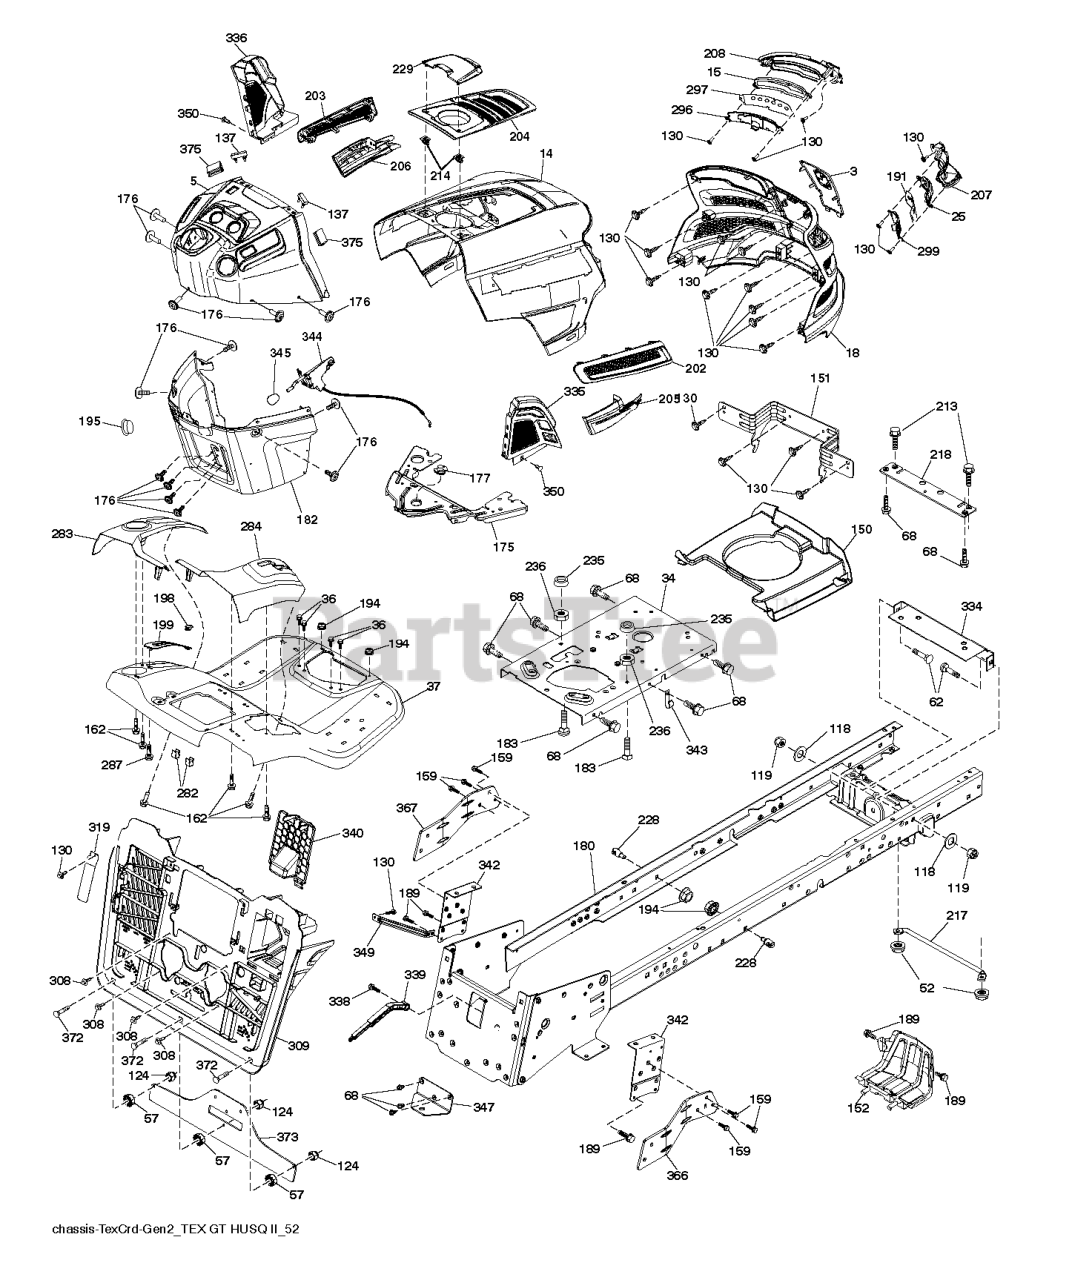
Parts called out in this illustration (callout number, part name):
3	APPLIQUE.SUBASM.GT.HUSQ.II
5	DASH.UPP.GT2.DUAL.RD.PT
14	HOOD.ASM.HUSQVARNA.GT.TEX.ORAN
15	LED LIGHT.LH
18	GRILLE.SUBSTRATE.2011.
25	LENS.RH
34	PLATE.ENGINE.10GA.CRD.GENII
36	SCREW 5/16"
37	FENDER.TEX.SRD.CRD.BASE
52	LOCKNUT
57	NUT
62	BOLT D
68	Screw 5/16-18 x 1/2 Hex, Self Tapping 5/16-18 x 1/2
118	WASHER
124	LOCKNUT.NYLOC.1/4-20
130	SCREW.#10 X 0.750.BOS
137	BUMPER DASH
150	AIR DUCT.GTV2(1.66"RING HEIGHT
151	BRACKET.PIVOT.HOOD.GT.HUSQ.II
152	SHIELD.BROWNING.PNT.GT.V2
159	SCREW, 3/8-16X3/4
162	SCREW.HI-LO.CONSOLE
175	PLATE.CROSSMEMBER.HUSQ
176	SCREW.#10-24X5/8.RN.QU
177	BUSHING STEERING
180	WELDMENT.CHASSIS.TEX.CRD.GEN.2
182	DASH DASH LOWER
183	BOLT.5/16-18X1-1/4 FULL THD
189	SCREW
191	INSERT INFLECT.RH
194	NUT LOCK HEX FLANGE 5/16-18
195	PLUG.HOLE.DASH.LOWER.12V.BLK
198	INDICATOR.DECK.LIFT.RED
199	PLATE DECK LIFT
202	VENT.SIDE.RH.GT.HUSQ.II.
203	VENT.SIDE.LH.GT.HUSQ.II.498
204	VENT.TOP.EXTERNAL.FILL.GT2.GRE
205	SIDE.TRIM.RH.GT.HUSQ.II
206	SIDE.TRIM.LH.GT.HUSQ.II.GRAY
207	LIGHT.BEZEL. RH
208	LIGHT.BEZEL.LH
213	BOLT
214	CLIP.RETAINER.TINNER.
217	ROD.PIVOT.HOOD
218	X-PIECE.HOOD.STOP.NON/
228	STUD.FASTNER.W/ANTI-ROTATE
229	LID.EXT.FILL.GT.HUSQ2.BLACK
235	SPACER FENDER
236	NUT.CENTERLOCK.5/16-
282	CLIP.RETAINER.CONSOLE.LT.HUSQ
283	CONSOLE.DECKLIFT.CRDII.498
284	CONSOLE.PEDAL.HYDRO
287	SCREW 1/4X20
296	LED LIGHT.LH
297	INSERT REFECT LH
299	LED LIGHT.RH
308	BOLT.5/16-18UNCX3/4 W/SEMS.BLK
309	BACKPLATE.ASM.TEX.CRD.GEN2.1
319	LEVER.BAG.CRDII.ANTIROTATION
334	BRACKET.ENGINE
335	COVER.LOWER.DASH.RH.BLACK
336	COVER-LH.LOWER.DASH.GT2.BLACK
338	BOLT BOLT SHOULDER
339	LEVER LEVER BAGGER
340	BATTERY.DOOR.TEX.CRD.GEN.2,1
342	SUPPORT.PNT.FENDER.CRD.TEX
343	CLIP CLIP
344	CONTROL.EZ.MULCH.TEX/CRD
345	RP KNOB.OVAL.TAPERED.3/8-16BLK
347	HITCH HITCH TOW TEX CRD GEN 2
349	BRACKET.SUPPORT.LRVB/CRD
350	CLIP.X-MAS.TREE
366	BRACKET.RH.FRONT.BAGGER.BLACK
367	BRACKET.LH.FRONT.BAGGER.BLACK
372	RHSNB, 1/4-20 X 1, GR5
373	REINFORCEMENT BACKPLATE. CRD B
375	BUMPER CLIP-ON. DASH 1"
